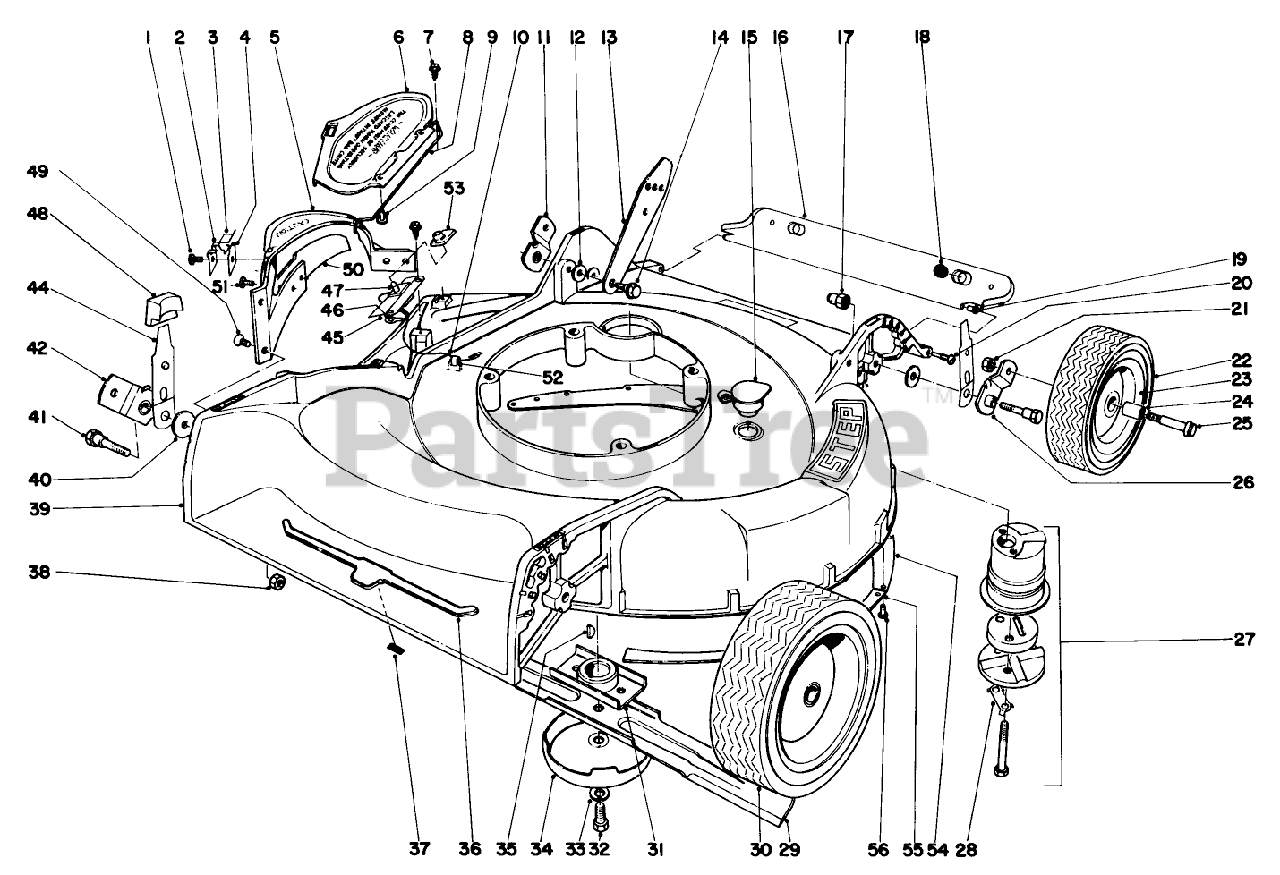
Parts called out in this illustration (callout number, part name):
2	Lower Clip
3	Upper Clip
4	Wear Plate
5	Deflector
6	Deflector Cover (Incl. Ref. Nos. 11 12)
7	SCREW-HWHTF
8	Hinge Pin
9	Rivet
10	Lead Wire
12	SPACER
14	SCREW-SHOULDER
15	WASHOUT PLUG
28	CLIP - LOCKING
33	WASHER-LOCK
35	KEY-WOODRUFF
36	Emblem, Bullshead
39	Housing (Incl. Ref. 54-56)
40	WASHER-PIVOT
41	5/16-18 PIVOT SCREW
45	Mounting Plate
46	Ground Wire
47	Switch
50	DefIector Bar
55	Secondary Skirt
